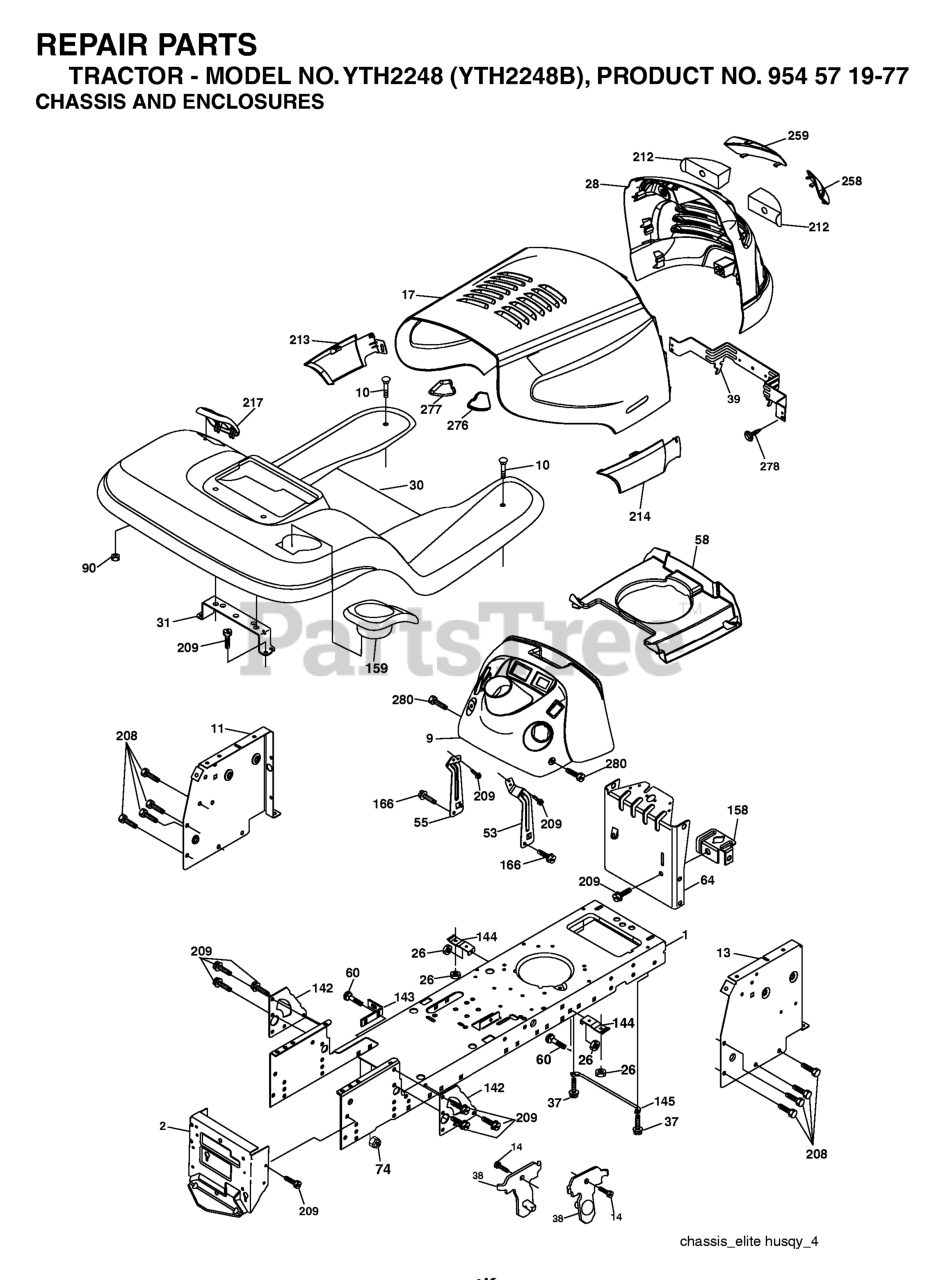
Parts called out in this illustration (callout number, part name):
1	CHASSIS STAMPING
2	DRAWBAR, 12GA
9	DASH
10	BOLT D
11	PANEL.DASH.LH.LTX
13	PANEL ASM, DASH RH
17	HOOD
20	PLATE MTG.BATTERY/FUEL TANK
23	BUSHING.SNAP.NYL.BLK.
26	NUT
28	GRILL/LENS ASSY ( YT MODEL)
30	FENDER STL W/CUPHOLDER
31	BRACKET.SUPPORT.FENDER
37	Screw 5/16-18 x 1/2 Hex, Self Tapping 5/16-18 x 1/2
38	BRACKET.ASM.PIVOT.MOWER.REAR
39	BRACKET PIVOT LASER
53	BRACKET DASH RH
55	BRACKET DASH LH
58	AIR DUCT
60	Bolt - Rd. Hd. Sq. Neckiage 3/8 16 x 3/4
64	DASH LOWER
90	NUT.PUSH.3/16
142	PLATE REINFORCEMENT
143	BRACKET, SWAYBAR CHASSIS
144	BRKT, FOOT REST
145	ROD PIVOT CHASSIS/HOOD
158	BRACKET PARKING BRAKE
159	GREY CUP HOLDER
166	SCREW
208	SCREW 3/8-16X1/2
209	SCREW, 3/8-16X3/4
212	INSERT LENS
213	SKIRT SIDE LH
214	SKIRT SIDE RH
217	CONSOLE FUEL WINDOW
219	SCREW
258	LENS ELITE CLEAR RH
259	LENS ELITE CLEAR LH
276	BUMPER HOOD RH
277	BUMPER HOOD LH
278	SCREW
280	SCREW THDROL 3/8-16 X 1-1/2
